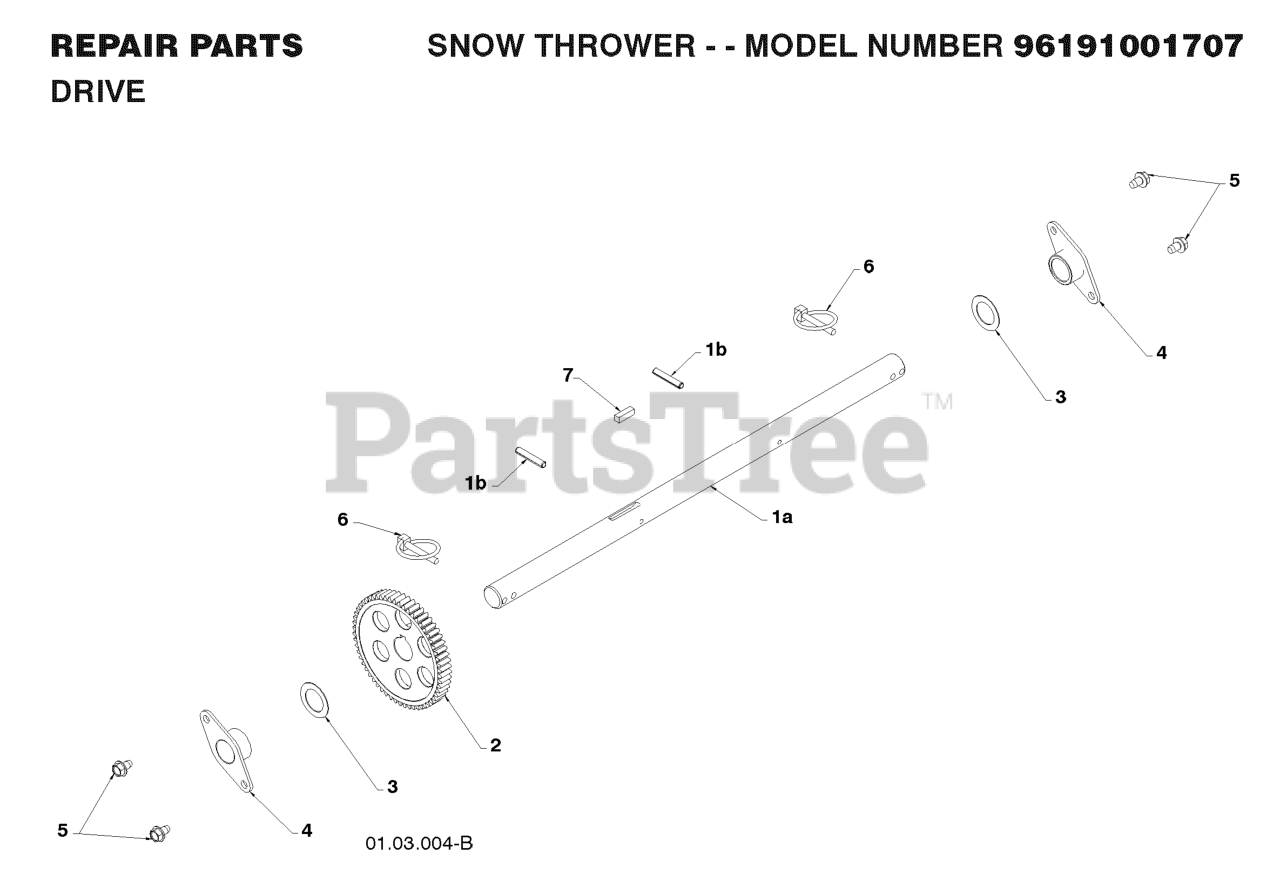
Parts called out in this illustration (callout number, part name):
1	AXLE.SHAFT.ASM.W/ROLPIN.NON-PS
1A	SHAFT.AXLE.16".SNOW
1B	PIN.ROLL.3/16
2	GEAR, AXLE (58T)
3	WASHER TRUST 1"
4	BEARING, AXLE
5	Screw 5/16-18 x 1/2 Hex, Self Tapping 5/16-18 x 1/2
6	PIN KLIK, 1/4
7	KEY, SQUARE 1/4 X .875
